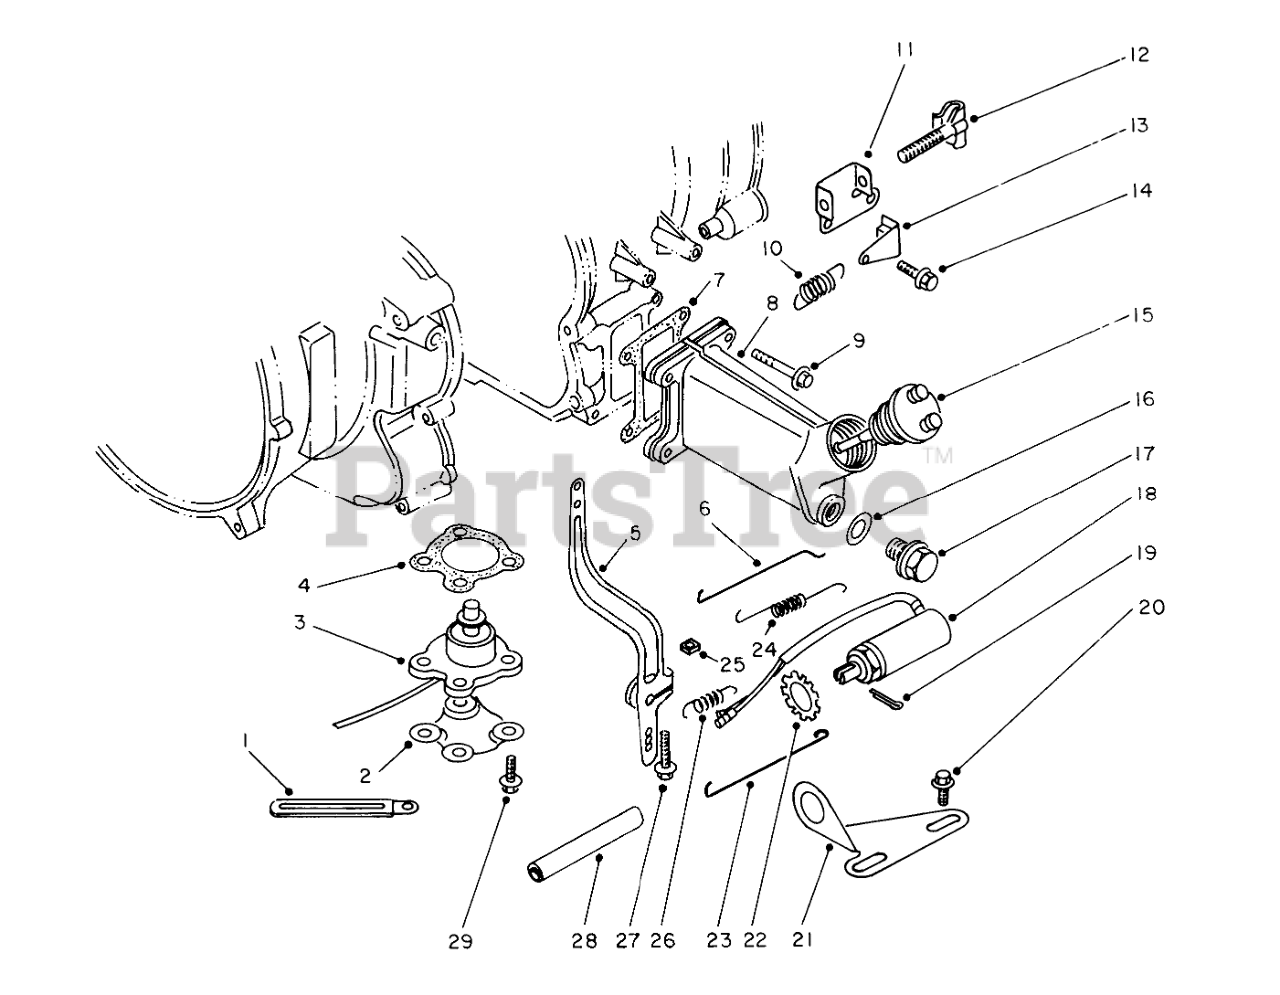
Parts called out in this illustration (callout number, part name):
1	Clamp
2	Plate
3	Oil Level Sensor
4	GASKET
5	Lever-Throttle Control
7	Gasket
8	Case-Oil Filler
10	Spring
11	Bracket
12	Bolt-Hook
15	Oil Gauge
16	GASKET
18	Solenoid
21	Bracket
22	Lockwasher
24	Spring
26	SPRING
